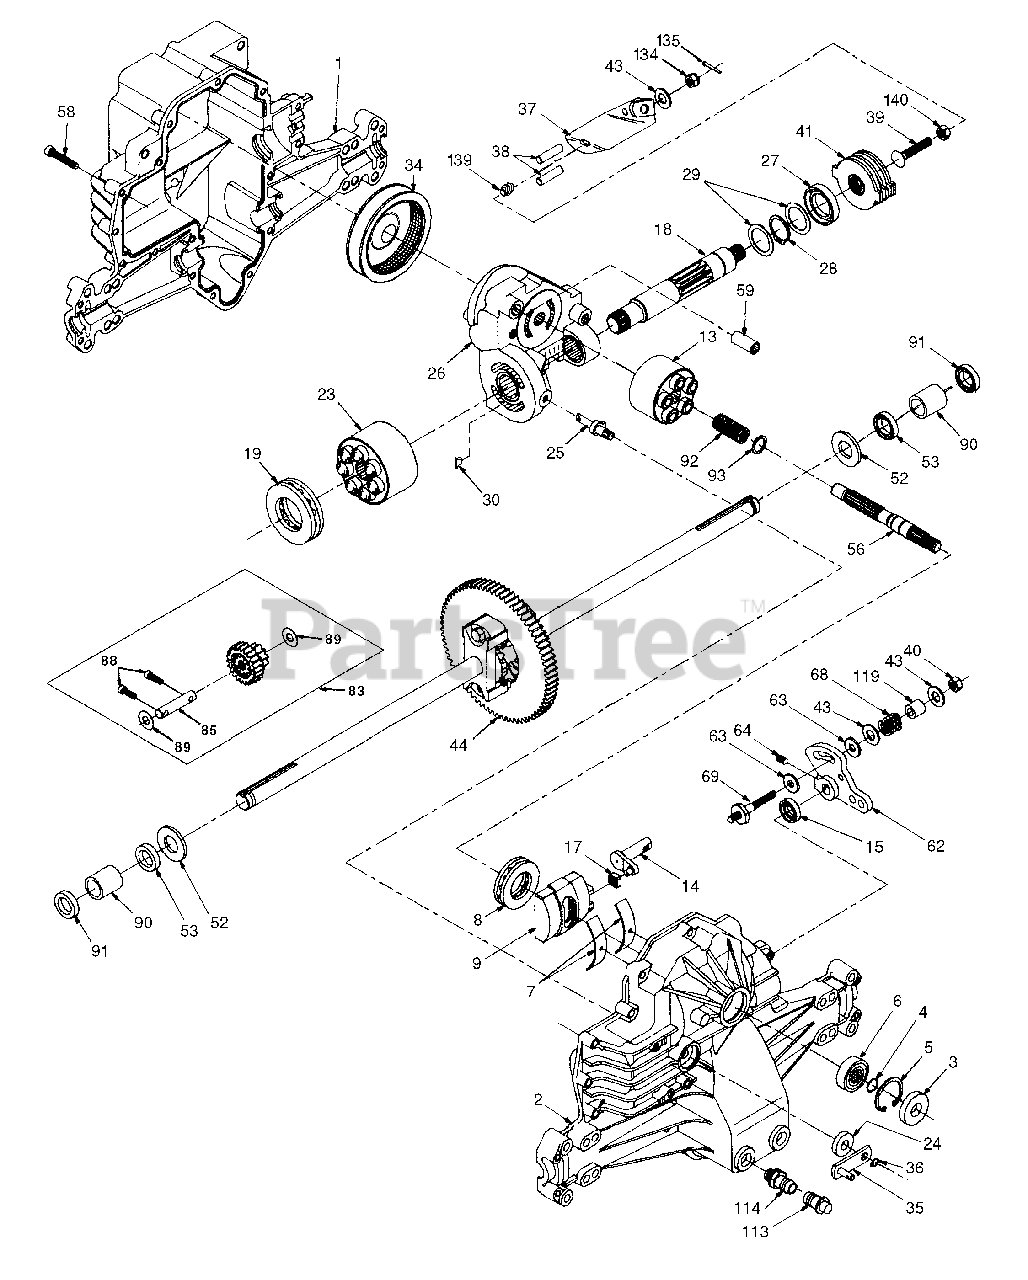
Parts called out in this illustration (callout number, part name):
1	Housing, Lower
2	Assembly, Upper Housing
4	Ring, Wire Retaining
5	Ring, Retaining
6	Bearing, Shaft Ball
7	Bearing, Cradle
8	Bearing, Thrust 30 x 52 x 13
9	Swashplate, Variable
13	Block, Cylinder Assembly
14	Arm, Trunnion
17	Guide, Slot
18	Shaft, Motor
19	Bearing, Thrust 42 x 68 x 16
23	Block, Cylinder Assembly
24	Seal, Lip 10 x 25 x 7
25	Actuator, Bypass
26	Center Section Assembly Kit
27	Seal, Lip 26 x 42 x 8
28	Ring, Retaining
29	Washer 26 x 35 x 1
30	Plate, Bypass
34	Oil Filter Element
35	Arm, Bypass
36	Ring, Retaining
37	Arm, Actuating
38	Pin, Actuating
39	Bolt 5/16-24 x 1-3/4
40	Locknut, Hex 5/16-24 UNJC
41	Brake Rotor/Stator Kit
43	Washer 7/16 x 7/8 x .060
44	Differential Assembly
52	Washer 3/4 x 1.5 x .13
53	Seal .75 x 1.25 x .250
56	Shaft, Input
58	Bolt 1/4-20 x 1.38
59	Pin .5 OD x .43 ID x .750
62	Arm, Control
63	Puck, Dampener
69	Stud 5/16-24
83	Jackshaft Assembly
88	Screw, Cap
89	Washer 7/16 x 1 x 1/2
90	Sleeve Bearing
91	Seal, Wiper
92	Spring, Block
93	Washer, Block Thrust
113	Cap, Vent Assembly
114	Fitting, O-Ring Assembly
119	Spacer
134	Nut, Castle 5/16-24
135	Pin, Cotter
139	Spring, Compression
140	Nut, Hex 5/16-24
